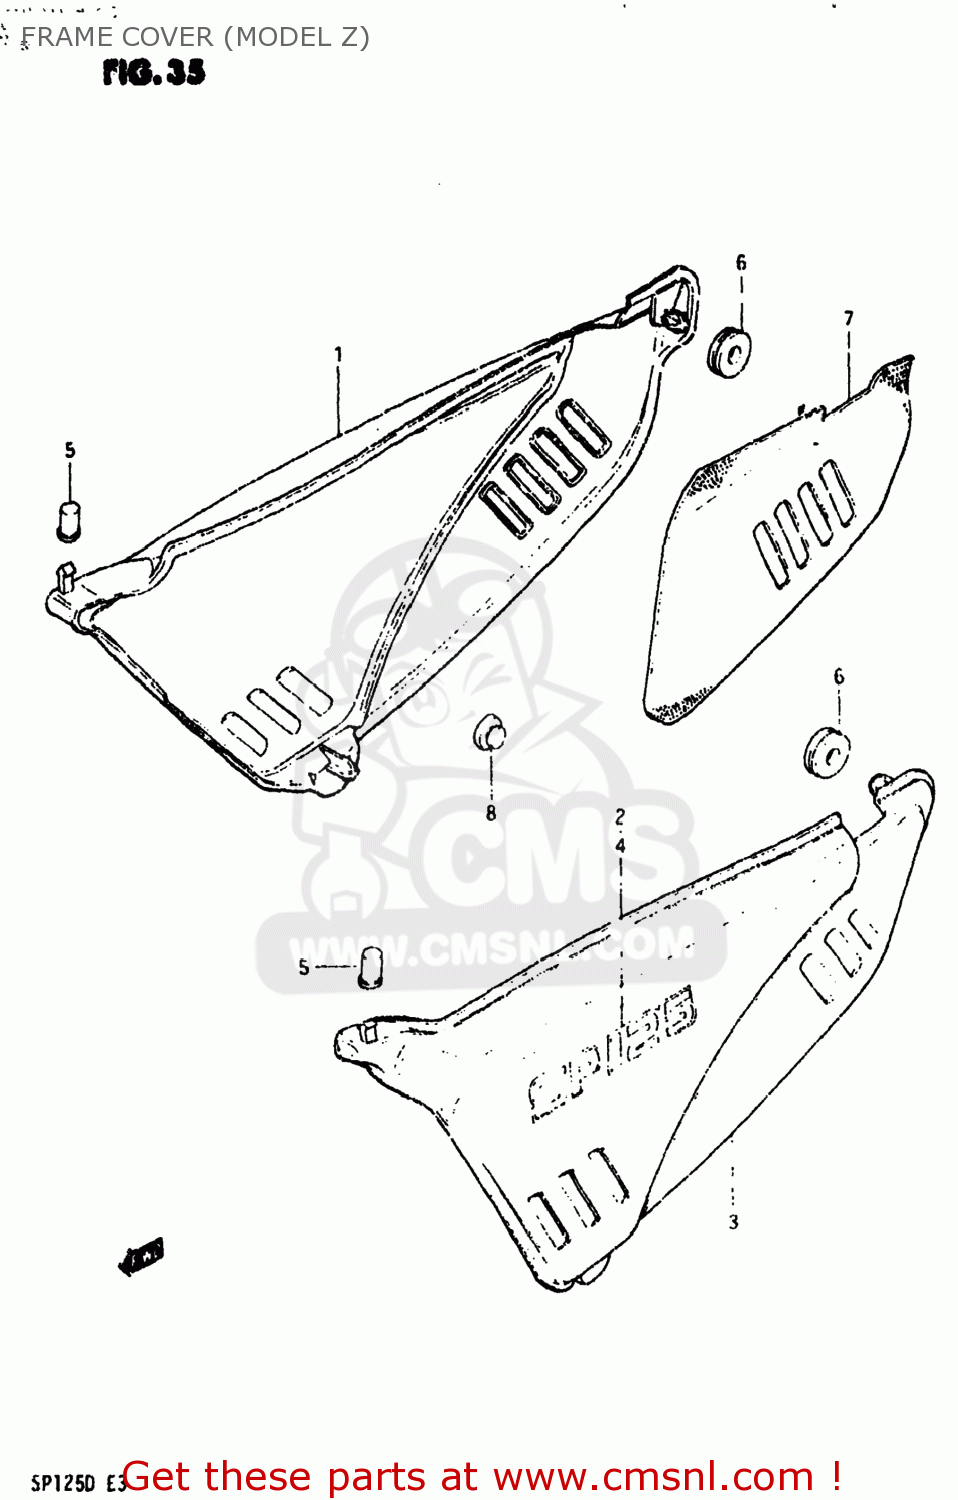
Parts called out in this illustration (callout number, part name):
1	COVER,FRAME,RIGHT
2	EMBLEM
3	COVER,FRAME,LEFT
4	EMBLEM
5	CUSHION
6	CUSHION
7	HEAT SHIELD,FRAME COVER
8	CUSHION
